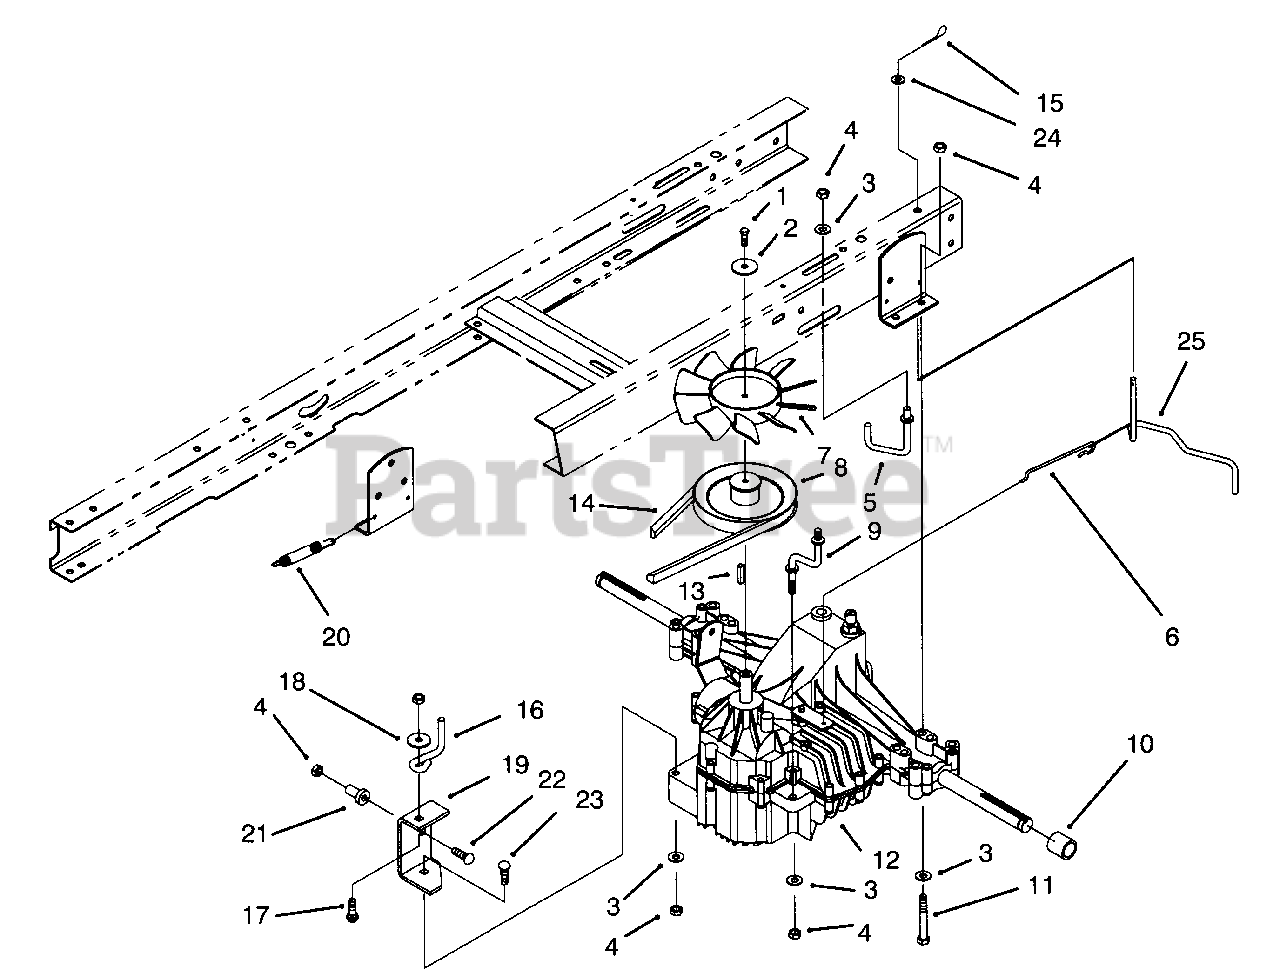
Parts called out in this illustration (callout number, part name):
1	Screw-Hex Hd. Cap
2	Washer-Flat
3	Washer-Flat
4	Nut-Lock
5	Guide-Trans. Belt L.H.
6	Wire-Bypass
7	Fan-Hydro
8	Pulley-Transaxle
9	Strap-Torque
10	Spacer-Wheel
11	Screw-Hex Hd. Cap
12	Transaxle
13	Key-Square
14	V-Belt-Transaxle
15	Pin-Hair Cotter
16	Belt Guide-Trans.
17	Bolt-Carriage
18	Washer-Fender
19	Bracket-Speed Control
20	Spring-Brake Return
21	Bushing-Flanged
22	Bolt-Carriage
23	Bolt-Carriage
24	Washer-Flat
25	Lever-Bypass
